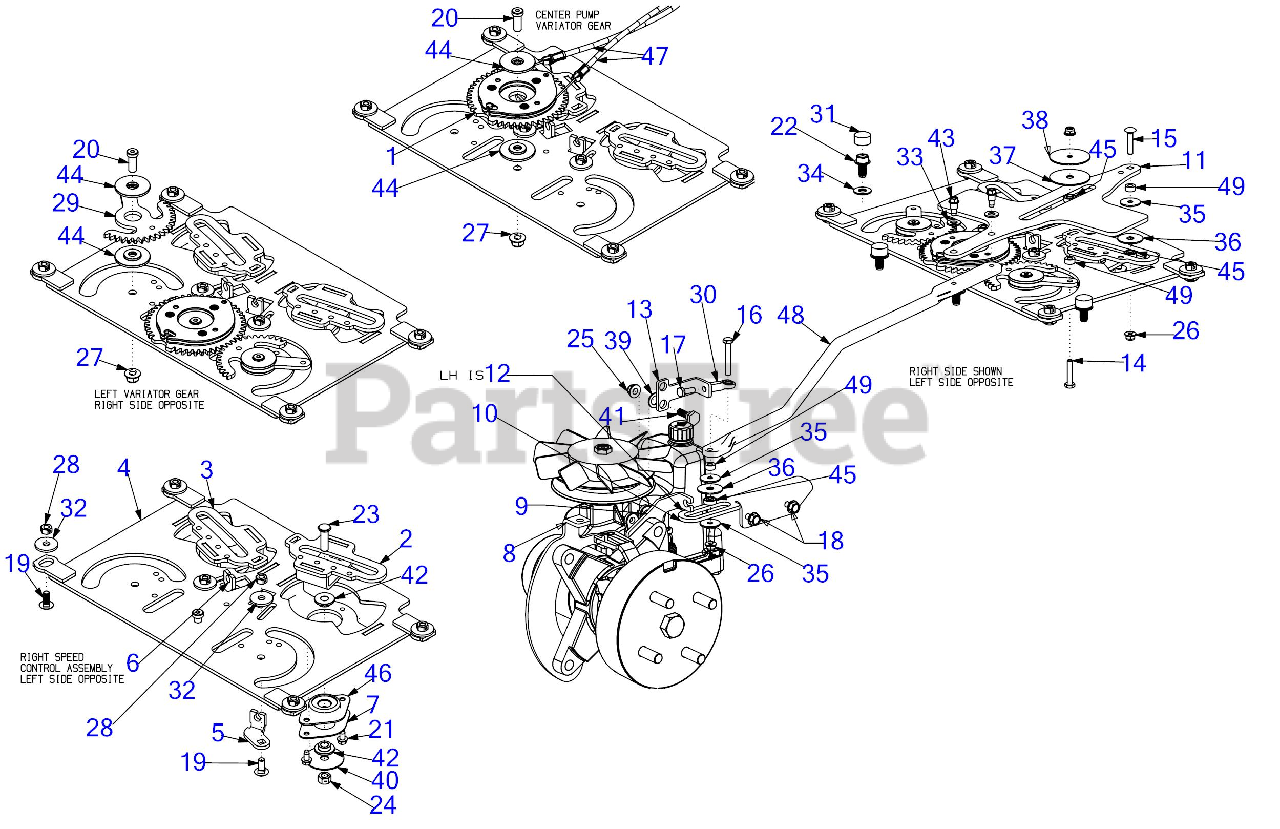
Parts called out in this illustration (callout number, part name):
1	PUMP GEAR
2	PUMP CONTROL CAM ASSEMBLY (RH)
3	PUMP CONTROL CAM ASSEMBLY (LH)
11	STEERING PUMP ACTUATOR ARM
13	PUMP CONTROL BRACKET
14	HEX SCREW 1/4-20 x 1.25
15	CARRIAGE BOLT 1/4-20 x 1.25 Gr5
16	HEX SCREW 1/4-20 x 1.75
17	HEX SCREW 1/4-28 x .75
18	SCREW 5/16-18 x .750
19	CARRIAGE BOLT 5/16-18 x .75
20	SCREW 3/8-16 x 1
21	SCREW 1/4-20 X.500
22	SCREW 3/8-16 x 3/4
23	SCREW 3/8-16 x 1.25 GR5
25	FLANGE LOCK NUT 5/16-18
26	FLANGE LOCK NUT
28	HEX NUT
29	STEERING GEAR YOKE
30	END ROD (RH)
31	SLIDE CAP
32	FLAT WASHER
33	FLAT WASHER
34	FLAT WASHER
35	FLAT WASHER
36	WASHER .355X1.25X.06THK
37	FLAT WASHER
38	FLAT WASHER
39	FLAT WASHER .469X.750X.054
40	HUB CAP WASHER .406 x 1.92 x .060
41	SHOULDER SCREW .437
42	SHOULDER SPACER
43	SHOULDER SCREW
44	SHOULDER SPACER
45	BALL BEARING .25 x .625 SPCL
46	BALL BEARING
47	TRANSMISSION CONTROL LINK CABLE
48	CONTROL PUMP ROD
